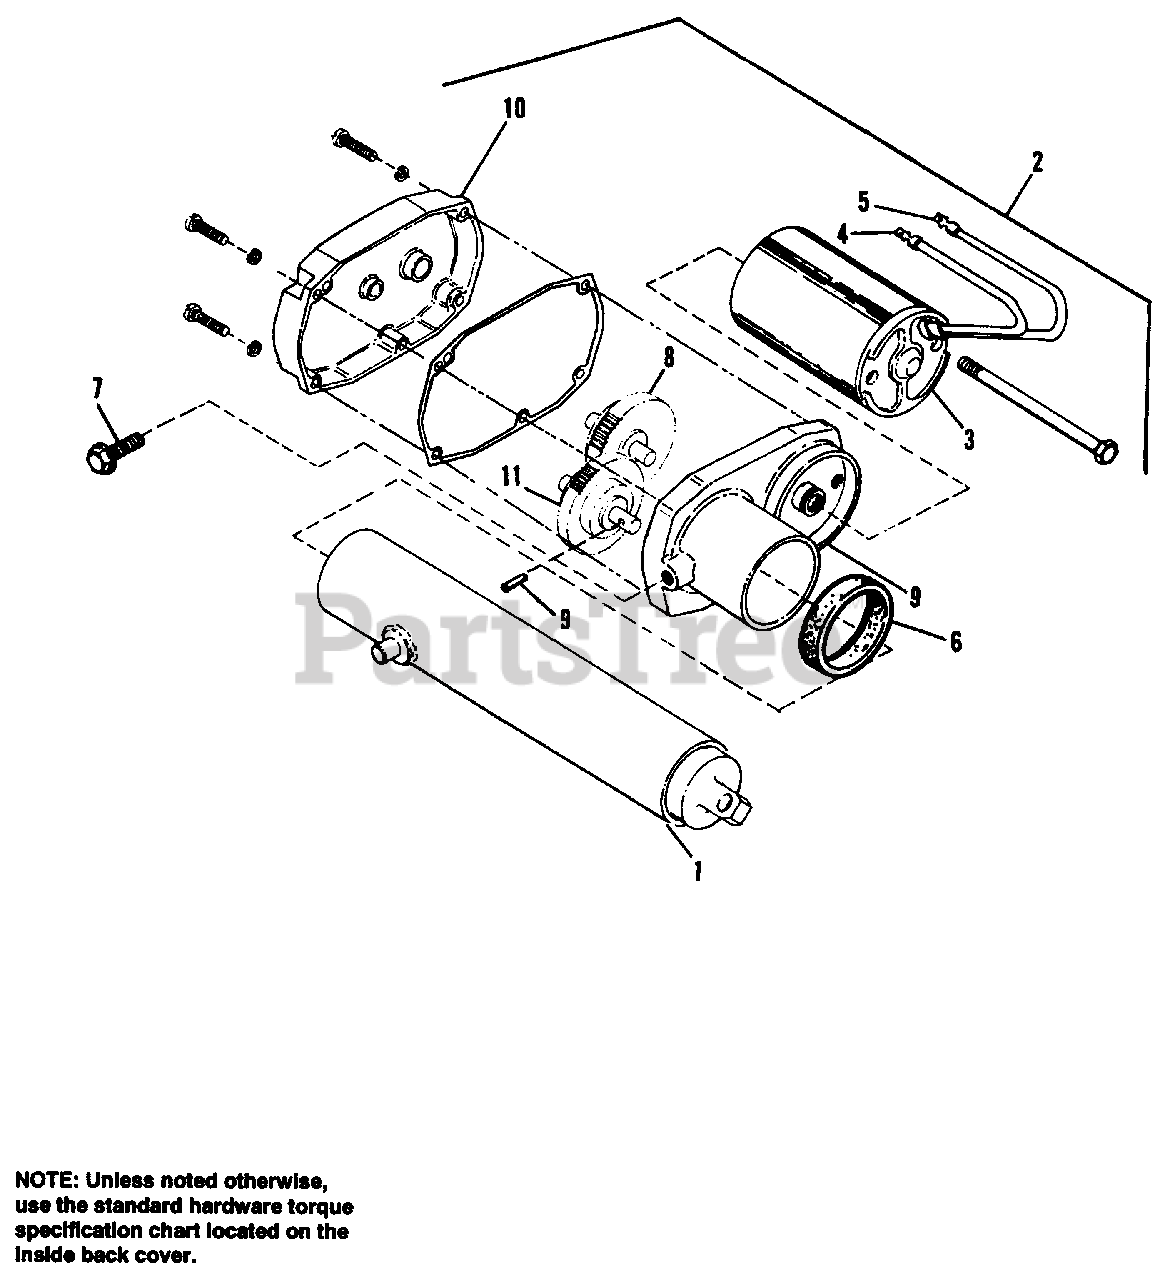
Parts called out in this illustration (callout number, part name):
1	LIFT TUBE ASSY.
2	MOTOR & GEAR BOX, 12V DC, 17:1 Ratio
3	MOTOR KIT, 12 VDC
4	BRUSH & LEAD (Rcd)
5	BRUSH & LEAD (Black)
6	SEAL, Outer Tube (Top)
7	CAPSCREW, Thd. Forming
8	GEAR ASSY., 2nd & 3rd
10	GASKET, Housing
11	OUTPUT GEAR & SLIP CLUTCH ASSY.
